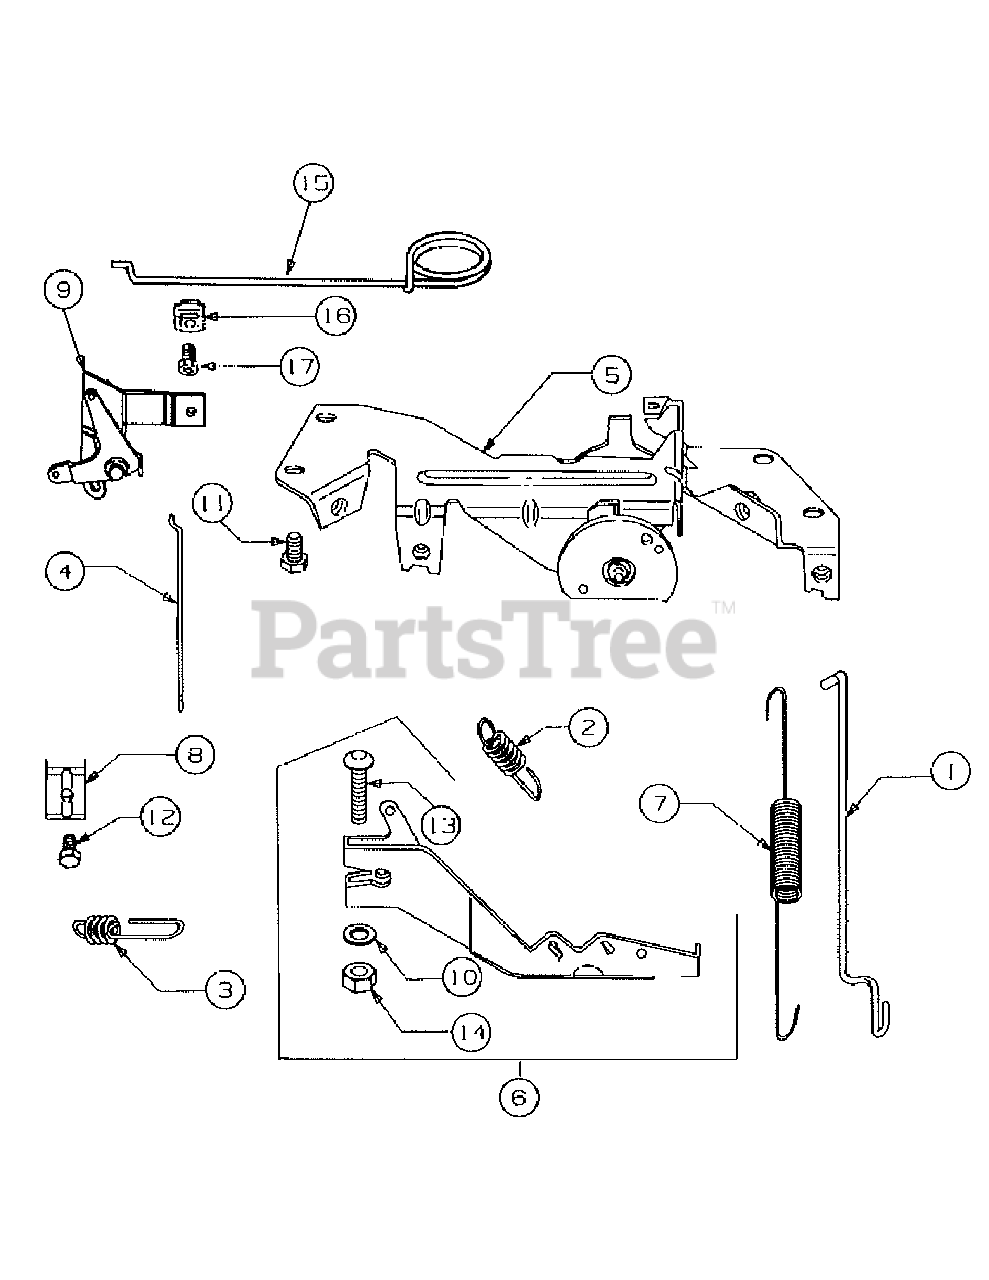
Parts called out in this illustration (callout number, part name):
1	Link, Governor
2	Spring, Governor
3	Spring, Governor Idle
4	Link, Choke
5	Bracket, Governor Control
6	Lever Assembly, Governor
7	Spring, Governor Link
8	Clamp, Casing
9	Bracket, Choke Control
11	Screw, Sem
12	Screw, Hex Head
14	Nut, Hex
15	Rod, Manual Choke
16	Clip Friction
17	Screw, Sem
